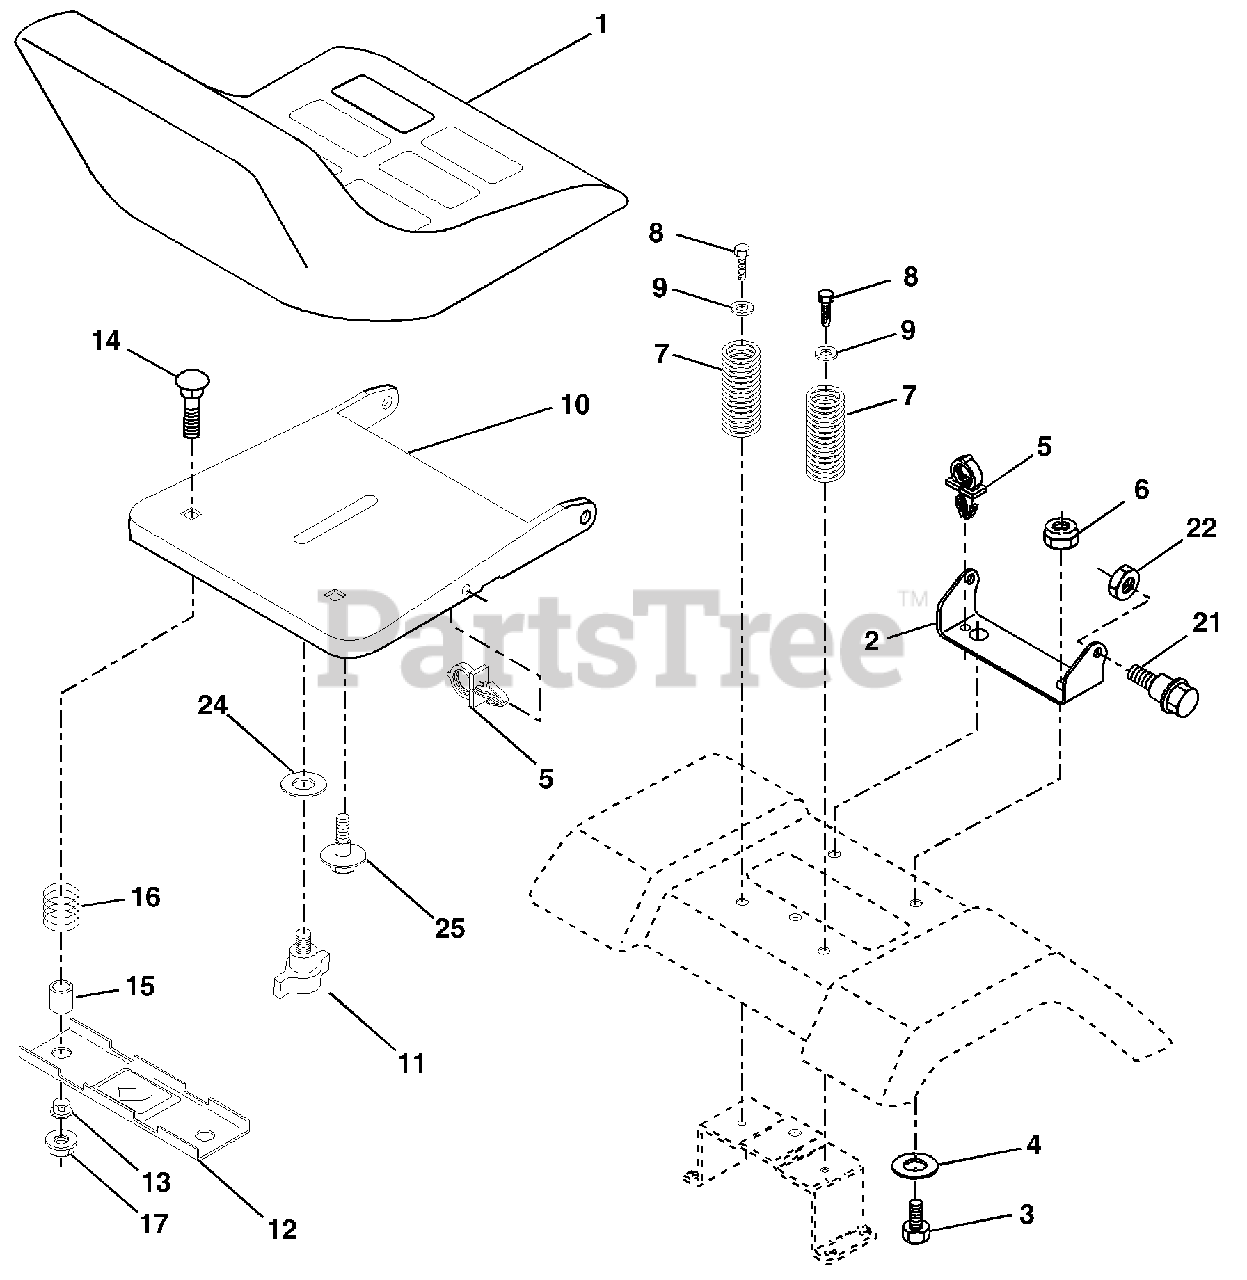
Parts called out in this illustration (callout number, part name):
1	Seat
2	Bracket Pivot Seat 8 720
3	Bolt Fin Hex 3/8-16 unc x 1
4	Washer 13/32 x 1 x 10 Ga.
5	Clip Push-In
6	Nut Hex w/Ins. 3/8-16 unc
7	Spring Seat Cprsn 2 250 Blk Zi
8	Screw 3/8-16 x 1-1/2 Smgml Tap/R Z
9	Washer 13/32 x 1 x 14 Ga.
10	Pan Seat
11	Knob Seat Adj. Wingnut
12	Bracket Mounting Switch
13	Bushing Snap Blk Nyl 50 Id
14	Bolt Rdhd Sqnk 1/4-2 x 1-1/2
16	Spring Cprsn
17	Nut Lock 1/4 Lge Flg Gr. 5 Zinc
21	Bolt Shoulder 5/16-18 unc-2a Blk DA
22	Nut Hex Lock W/Ins 5/16-18
24	Washer 17/32 x 13/16 x 12 Ga.
25	Bolt Shoulder 5/16-18 x 62
